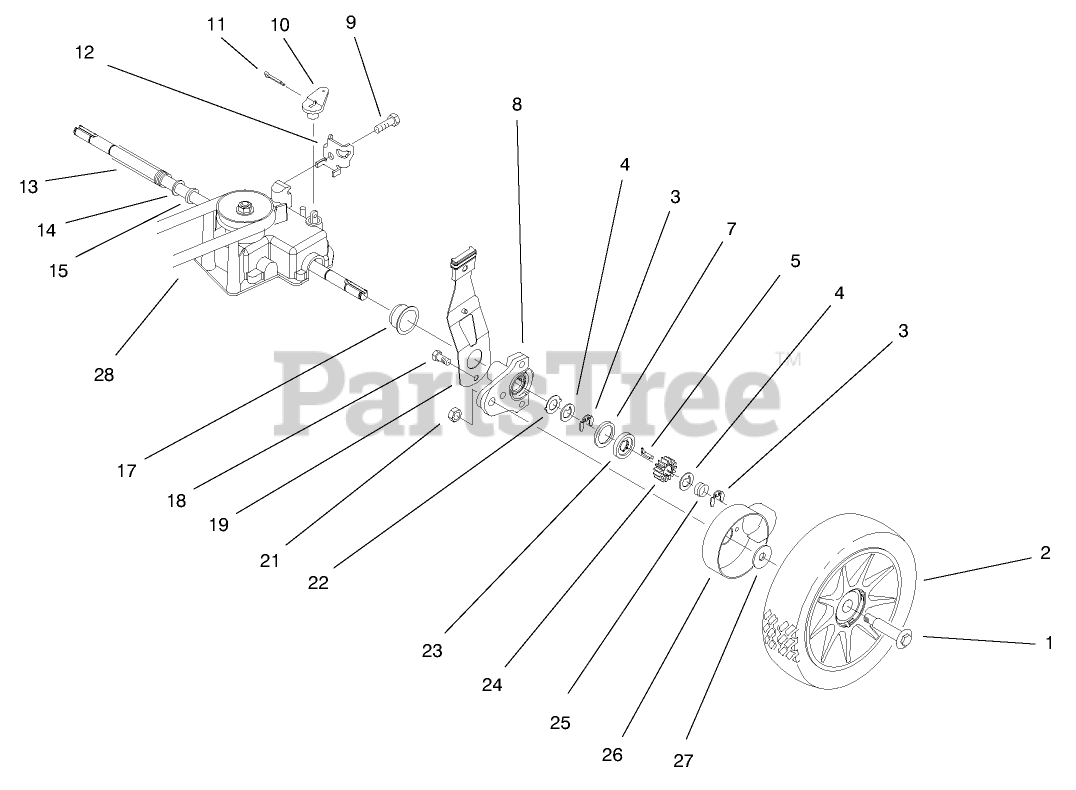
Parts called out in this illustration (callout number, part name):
1	BOLT-SHOULDER
2	WHEEL AND GEAR ASM
3	RING-CLIP, LOCKING
4	WASHER-THRUST, KEYED
5	KEY-ROCKING, LH
7	RING-FRICTION
8	REAR HEIGHT ADJUSTMENT ARM ASM
9	SCREW-HWHTF
10	LEVER-SHIFT
11	PIN-COTTER
12	CLAMP-CABLE
13	COVER-SHAFT, DRIVE
14	WASHER
15	WASHER
17	RING-ISOLATOR
18	SCREW-HWH
19	LH REAR SPRING ARM ASM
21	NUT-JAM, LOCKING
22	WASHER-ARM, PIVOT
23	WASHER-CLUTCH
24	GEAR-PINION
25	SPRING-COMPRESSION
26	COVER-WHEEL
27	WASHER-STEPPED
28	V-BELT
